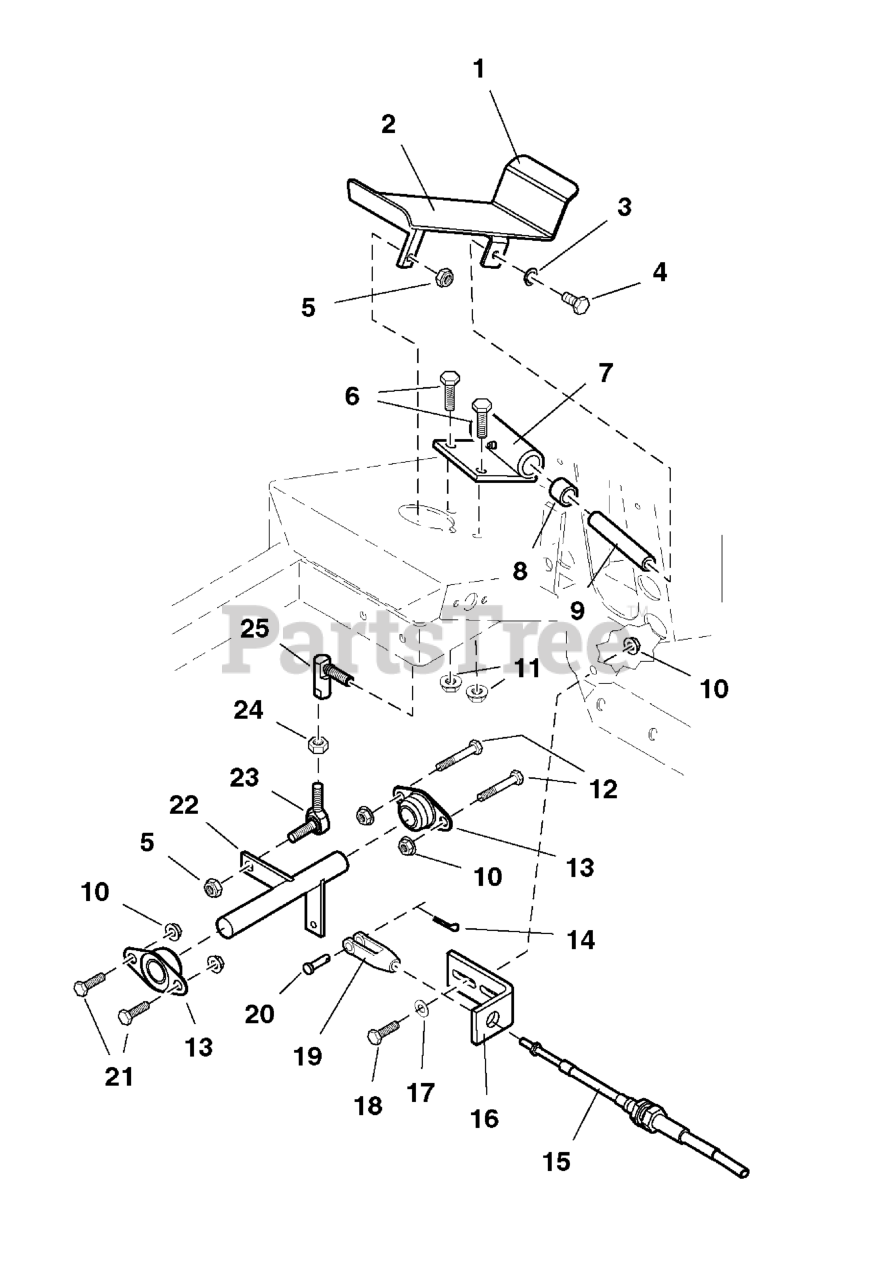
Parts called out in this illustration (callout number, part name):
1	FOOT CONTROL PEDAL
2	SAFETY WALK
3	WASHER, 3/8" Lock
4	BOLT, 3/8-16 X 3/4" GD5 CZ
5	NUT, 3/8-24 Hex Nylon Lock
6	BOLT, 3/8-16 X 1" GD5 CZ
7	FOOT PEDAL PIVOT MOUNT, Complete
8	BUSHING, PLASTIC,3/4 X 1 X 3/4
9	SHAFT, Pedal Pivot
10	NUT, 5/16-18 HEX SERRATED FLANGE (LARGE)
11	NUT, 3/8-16 Hex Serrated Flange
12	BOLT, 5/16-18 x 2-1/2
13	BEARING, Flange
14	COTTER PIN, 1/16" x 1/2"
15	CABLE, Speed Control
16	CABLE BRACKET
17	WASHER, 5/16" SAE
18	BOLT, 5/16-18 X 1 GD5 YZ
20	CLEVIS PIN, 1/4 x 1
21	BOLT, 5/16-18 X 3/4 GD5
22	BELL CRANK
23	BALL JOINT, 3/8-24 Male, Studded
24	NUT, 3/8-24 Hex
25	BALL JOINT, 3/8" Female Studded
